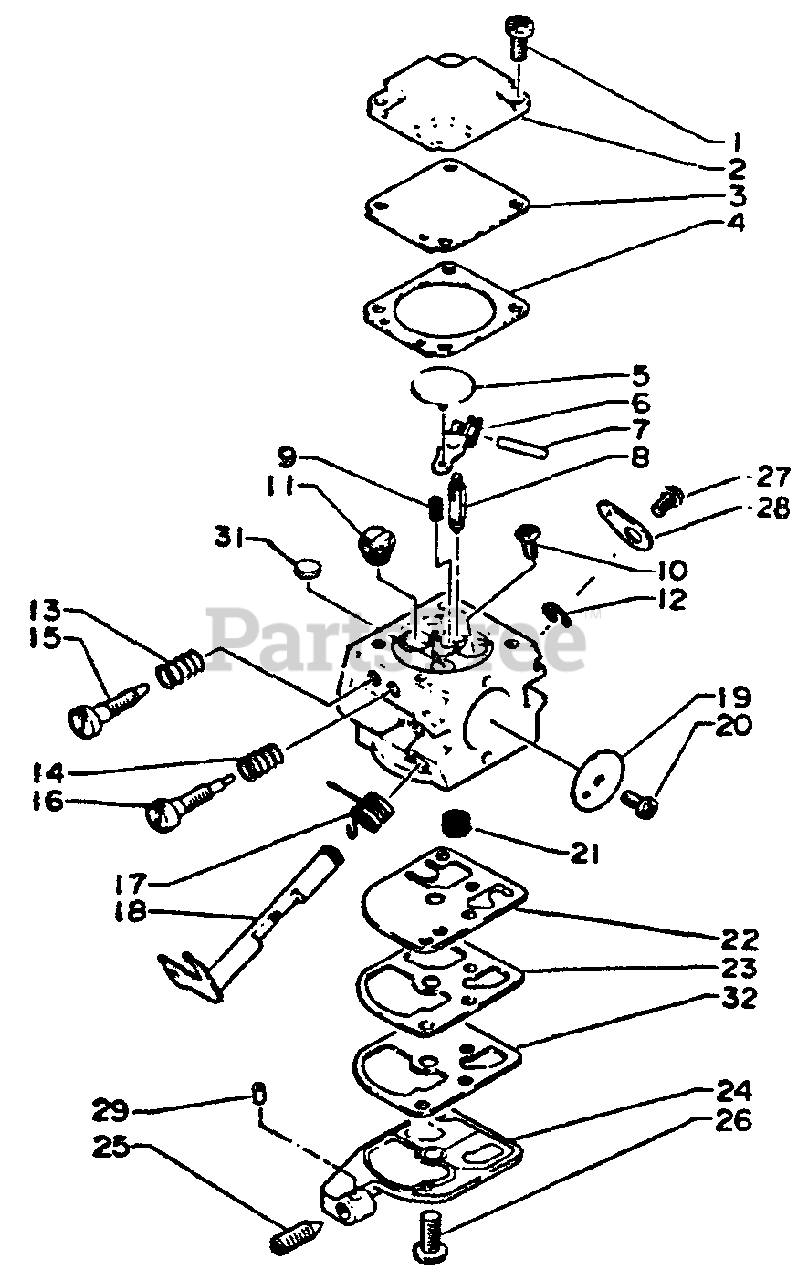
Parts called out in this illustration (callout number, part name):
1	SCREW
2	COVER, DIAPHRAGM
3	DIAPHRAGM
4	GASKET, DIAPHRAGM
5	DISK
6	LEVER, METERING
7	PIN
9	SPRING
11	NOZZLE, CHECK VALVE
15	NEEDLE, HIGH SPEED
16	NEEDLE, IDLE
17	SPRING, THROTTLE RETURN
18	SHAFT, THROTTLE
19	VALVE, THROTTLE
20	SCREW
22	DIAPHRAGM, PUMP
23	GASKET, FUEL PUMP
24	BASE, PUMP
25	SCREW, IDLE ADJUST
28	LEVER, THROTTLE
29	PIECE, FRICTION
31	PLUG, WELCH
32	REBUILD KIT
32	DIAPHRAGM/GASKET KIT
